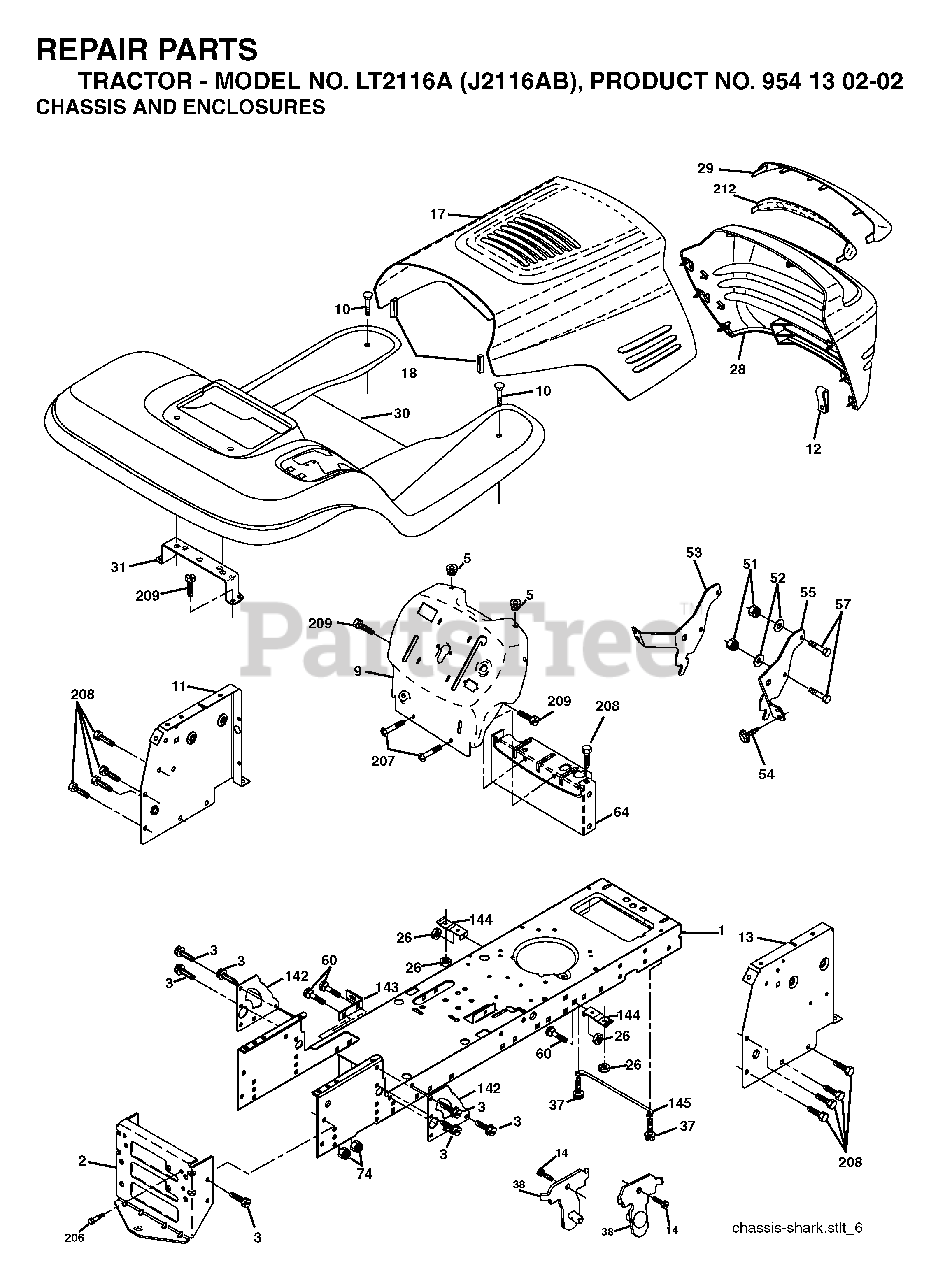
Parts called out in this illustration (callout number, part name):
1	CHASSIS STAMPING
2	DRAWBAR, 12GA
3	SCREW 3/8-16X3/4
5	BUMPER.RUBBER.HOOD
10	BOLT D
11	PANEL.DASH.LH.LTX
13	PANEL ASM, DASH RH
18	BUMPER.HOOD.LARGE.1.75"
26	NUT
38	BRACKET.ASM.PIVOT.MOWER.REAR
51	LOCKNUT
57	BOLT
58	AIR DUCT P/L/LT
64	DASH LOWER
74	LOCKNUT
142	PLATE REINFORCEMENT
143	BRACKET, SWAY BAR
144	BRKT, FOOT REST
145	ROD PIVOT CHASSIS/HOOD
206	SHOULDER BOLT 5/16-18TT
207	SCREW, 5/16-18 X 1/2
208	SCREW 3/8-16X1/2
209	SCREW, 3/8-16X3/4
